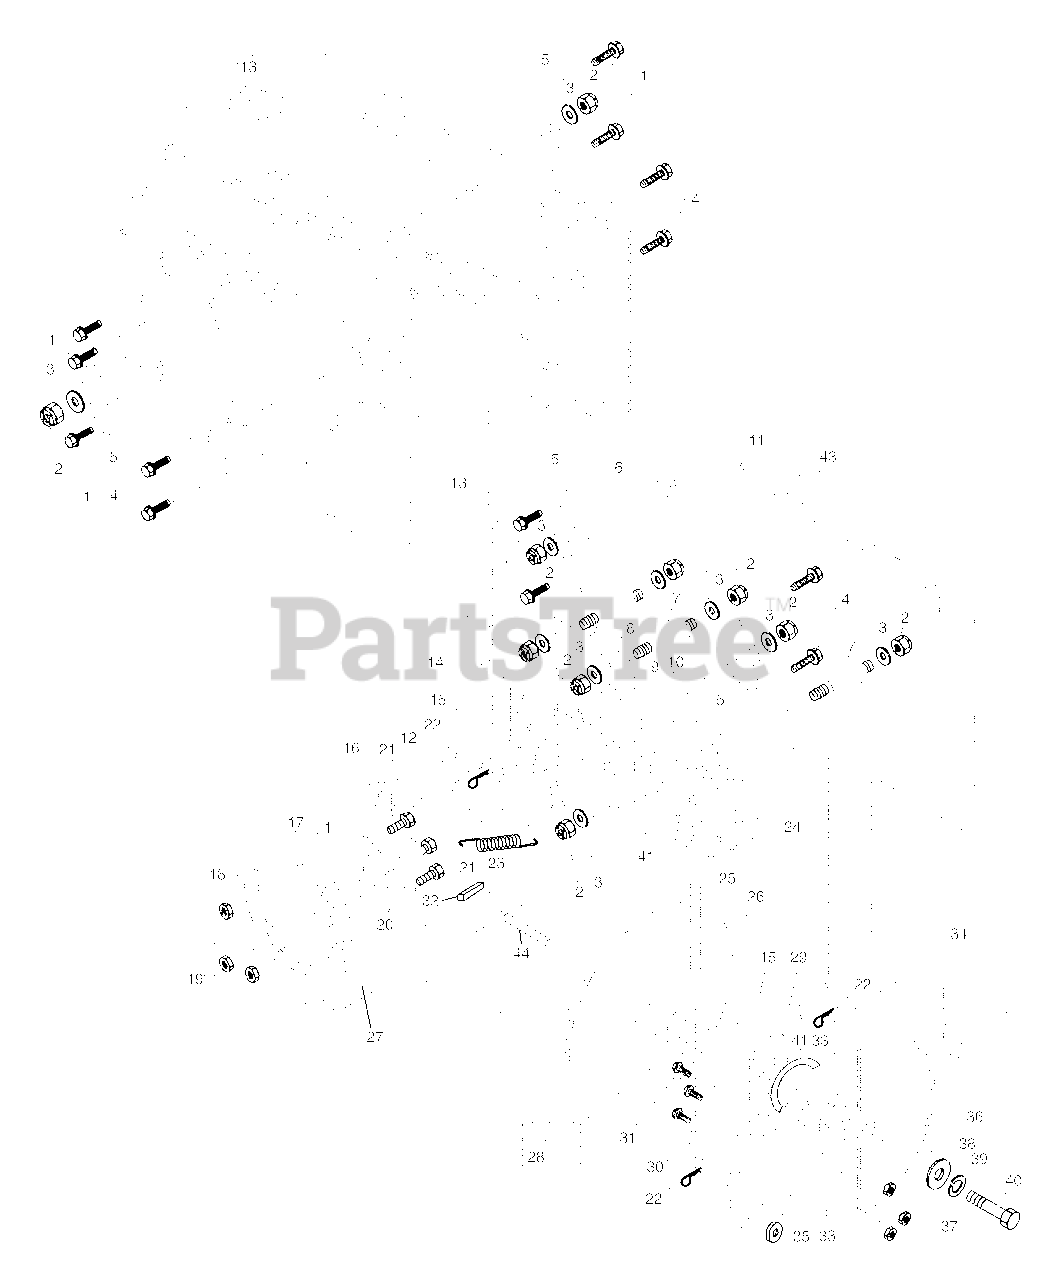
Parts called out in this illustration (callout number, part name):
1	Screw, Hex Head 5/16-18 x 3/4
2	Nut, Lock 5/16-18
3	Washer, Flat
4	Screw, Hex Head 5/16-18 x 1/2
5	Bearing, Flange
6	Shaft, Auxiliary
7	Spacer, Plate
8	Plate, Auxiliary
9	Gear, Intermediate (12/58)
10	Gear, Pinion
11	Rod, Clutch
12	Shaft, Long, Hex
13	Pin, Pivot
14	Lever, Shifter / Wheel
15	Trunnion Bearing Assembly
16	Bracket, Pivot, Shift
17	Ring, Rubber Wheel
18	Plate, Rubber Wheel
19	Nut, Lock 5/16-18
20	Hub, Rubber Wheel
21	Screw, Hex Head 5/16-18 x 7/8
22	Retainer, Hairpin
23	Spring, Bias
24	Gear, Axle (58 Teeth)
25	Pin, Pivot Lever
26	Plate Assembly, Drive
27	Shaft, Axle
28	Shaft, Short Hex
29	Lever, Shifter Plate
30	Bracket, Shifter Support
31	Bolt, Carriage 5/16-18 x 5/8
32	Key, Square 1/4 x 1/4 x 7/8
33	Bearing, Flange
34	Plate, Drive Mounting
35	Spacer, Bearing
36	Pulley, Traction Drive
37	Nut, Lock 5/16-18
38	Washer, Flat
39	Washer, Lock 5/16
40	Screw, Hex Head 5/16-18 x 3/4
41	Ring, Retaining
43	Spring, Return
